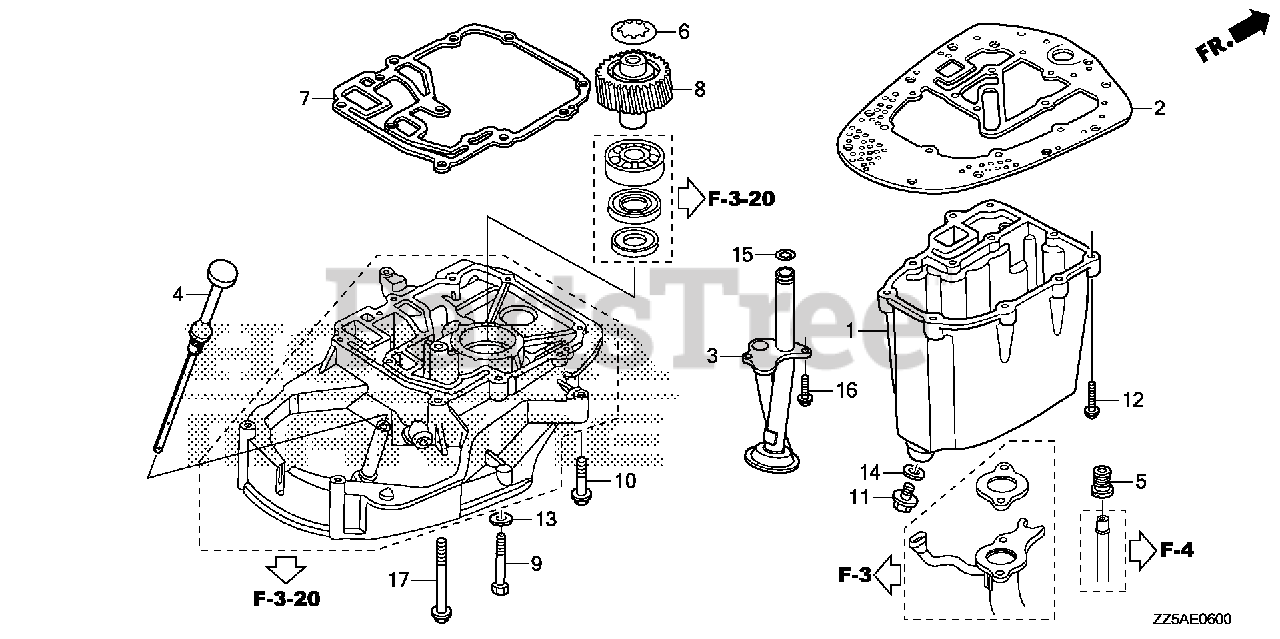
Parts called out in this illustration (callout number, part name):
1	PAN, OIL *TGRAY* (GRAY)
2	GASKET, OIL PAN
3	STRAINER, OIL
4	DIPSTICK, OIL
5	GROMMET, WATER TUBE
6	SPRING, THRUST
7	GASKET, PRIMARY GEAR CASE
8	GEAR, PRIMARY DRIVEN (33T)
9	BOLT, HEX. (8X55)
10	BOLT, FLANGE (8X35)
11	BOLT, DRAIN PLUG
12	BOLT, FLANGE (6X25) (SUS-D)
13	WASHER, PLAIN (8MM)
14	WASHER, DRAIN PLUG (12MM)
15	O-RING (13.8X2.5)
16	BOLT, FLANGE (6X16)
17	BOLT, FLANGE (8X75)
